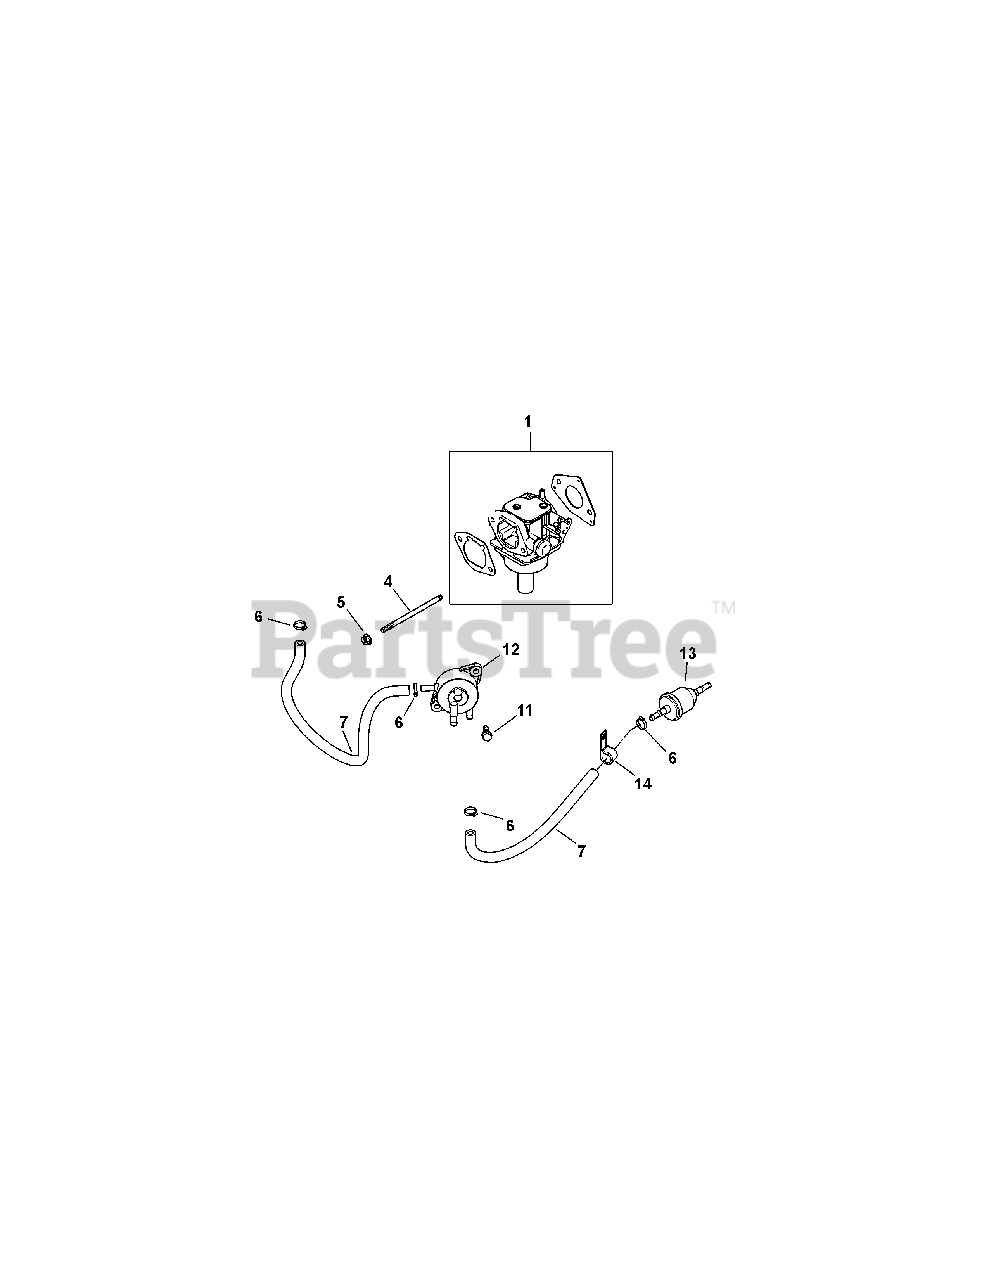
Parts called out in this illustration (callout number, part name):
1	Carburetor Kit, 22mm KEIHIN (Inc.2 & 3)
4	Stud, M6 x 1.0 x 106
5	Flg. Nut, M6 x 1.0
6	Hose Clamp, 1/2
7	Fuel Line
11	Tap Screw, M6 x 1.7 x 18
